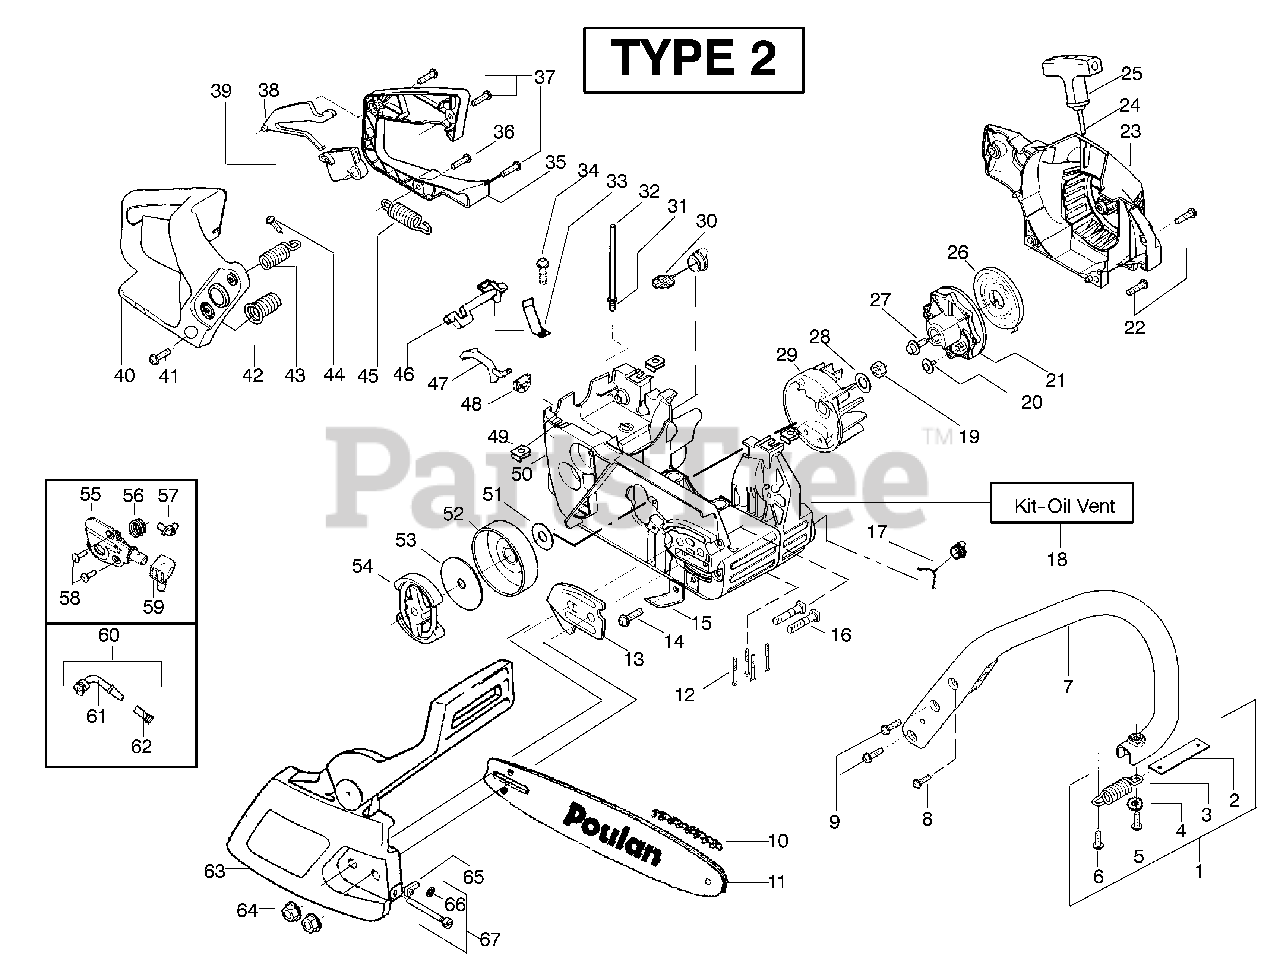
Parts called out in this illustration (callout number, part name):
1	Assy.-Isolator
2	Limiter Strap
3	Spring-Isolator
4	Washer
7	Front Handle
10	Chain - 18"
11	Bar - 18"
13	Plate-Bar Mount.
15	Chain Catcher
16	Bolt-Bar
17	Assy-Oil Cap
18	Kit-Oil Vent
19	Nut-Flywheel
21	Starter Pulley
23	Housing-Fan
24	Kit - Rope
25	Handle-Starter
26	Spring-Recoil
28	Washer-Flywheel
29	Assy-Flywheel
30	Assy-Fuel Cap
31	Fitting-Fuel Line
32	Kit-Fuel Line
33	Spring-Switch
35	Cover-Rear Handle
38	Throttle Lockout
39	Trigger-Throttle
40	Handle - Rear
41	Screw
42	Assy Isolator-Lower
43	Kit-Isolator
45	Spring-Isolator
46	Lever-Switch
47	Lever-Choke
48	Grommet-Knob
49	Nut-"U"-Type
50	Assy-Chassis fuel lines and caps
51	Washer-Thrust
52	Assy.-Clutch Drum w/bearing
53	Washer-Clutch
54	Assy. Clutch
55	Kit - Oil Pump
56	Gear-Worm Spring
57	Elbow-Oil Pickup
59	Seal Block
60	Assy-Oil Pick-up
61	Pick-up Oiler
62	Filter-Oil
63	Assy.-Chain Brake
64	Nut-Bar Mounting
65	Pin-Bar Adjust
66	Retainer
67	Kit-Bar Adjusting
